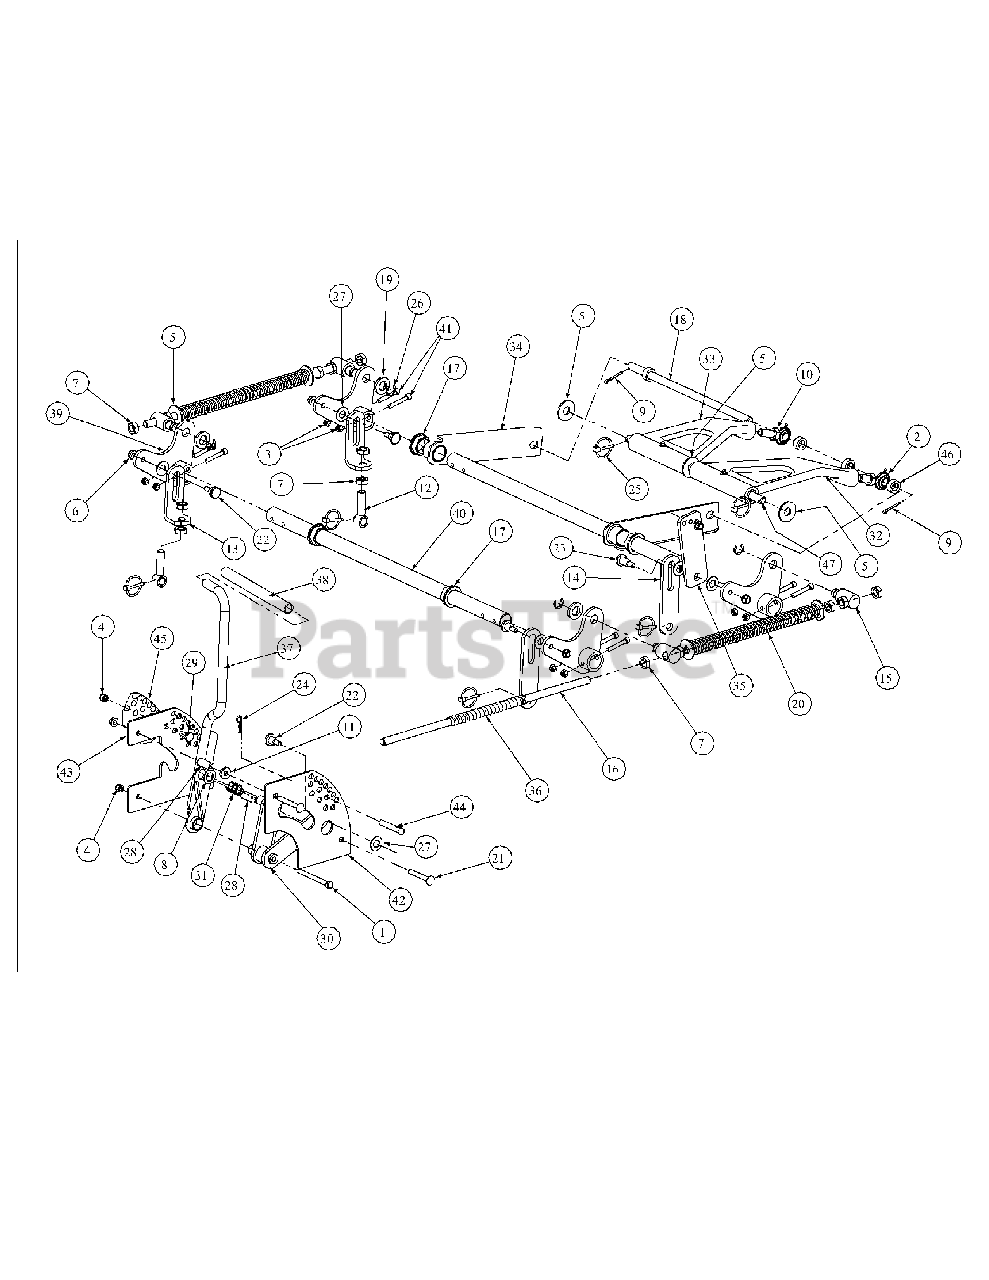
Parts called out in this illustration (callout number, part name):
1	Hex Cap Screw, 3/8-16, 3.75
2	Rod End, Male
3	Nut, 5/16-18, Nylock
4	Nylock Insert Lock Nut, 3/8-16
5	Flat Washer, 5/8
6	Hex Nut, Flange Lock, 3/8-16
7	Jam Nut, 5/8-11
8	Flat Washer, .06, .776, 1.25
9	Cotter Pin, 3/16 x 1-1
10	Jam Nut, 5/8-18
11	Idler Washer
12	Eye Bolt, 5/8ID
13	Eye Bolt Mount Link, 5/8 ID
14	Deck Link
15	Ferule Lift
16	Lift Connector Rod
17	Hex Flange Bearing, 1.25 ID
18	Front Lift Link, Rod Mount
19	Spacer, .812 ID x .268 Lg.
20	Lift Compression Spring
21	Carriage Bolt, 3/8-16, 2.75
22	Shoulder Screw, 0.625 OD x .437 Lg.
23	Shoulder Screw, 0.625 OD x .830 Lg.
24	Cotter Pin, .148 x 3.00
25	Linch Pin, 3/16 Dia.
26	E Clip, 3/4 Dia.
27	Nylon Flat Washer, 5/8
28	Spacer, .39 ID x .63 OD x 1.442
29	Shoulder Screw, .50 OD x 0.27
30	Lift Pivot Assembly
31	Lift Handle Spring
32	Bearing Lift Brace Assembly, Right Hand
33	Bearing Lift Brace Assembly, Left Hand
34	Front Frame Strut Assembly
35	Lift Link Adjustment
36	Hose, 5/8 ID 13/16 OD, 8" LG
37	Lift Handle Assembly
38	Lift Handle Grip
39	Bellecrank Weldment Assembly
40	Deck Lift Shaft
41	Socket Head Cap Screw, 5/16-18 x 2
42	Outer Lift Index Plate
43	Inner Lift Index Plate
44	Clevis Pin, .438 Dia. x 2.625 Lg.
45	Decal Height Indicator
46	Spacer, .630 ID x 1.06 OD x .440
47	Lift Link Rod
